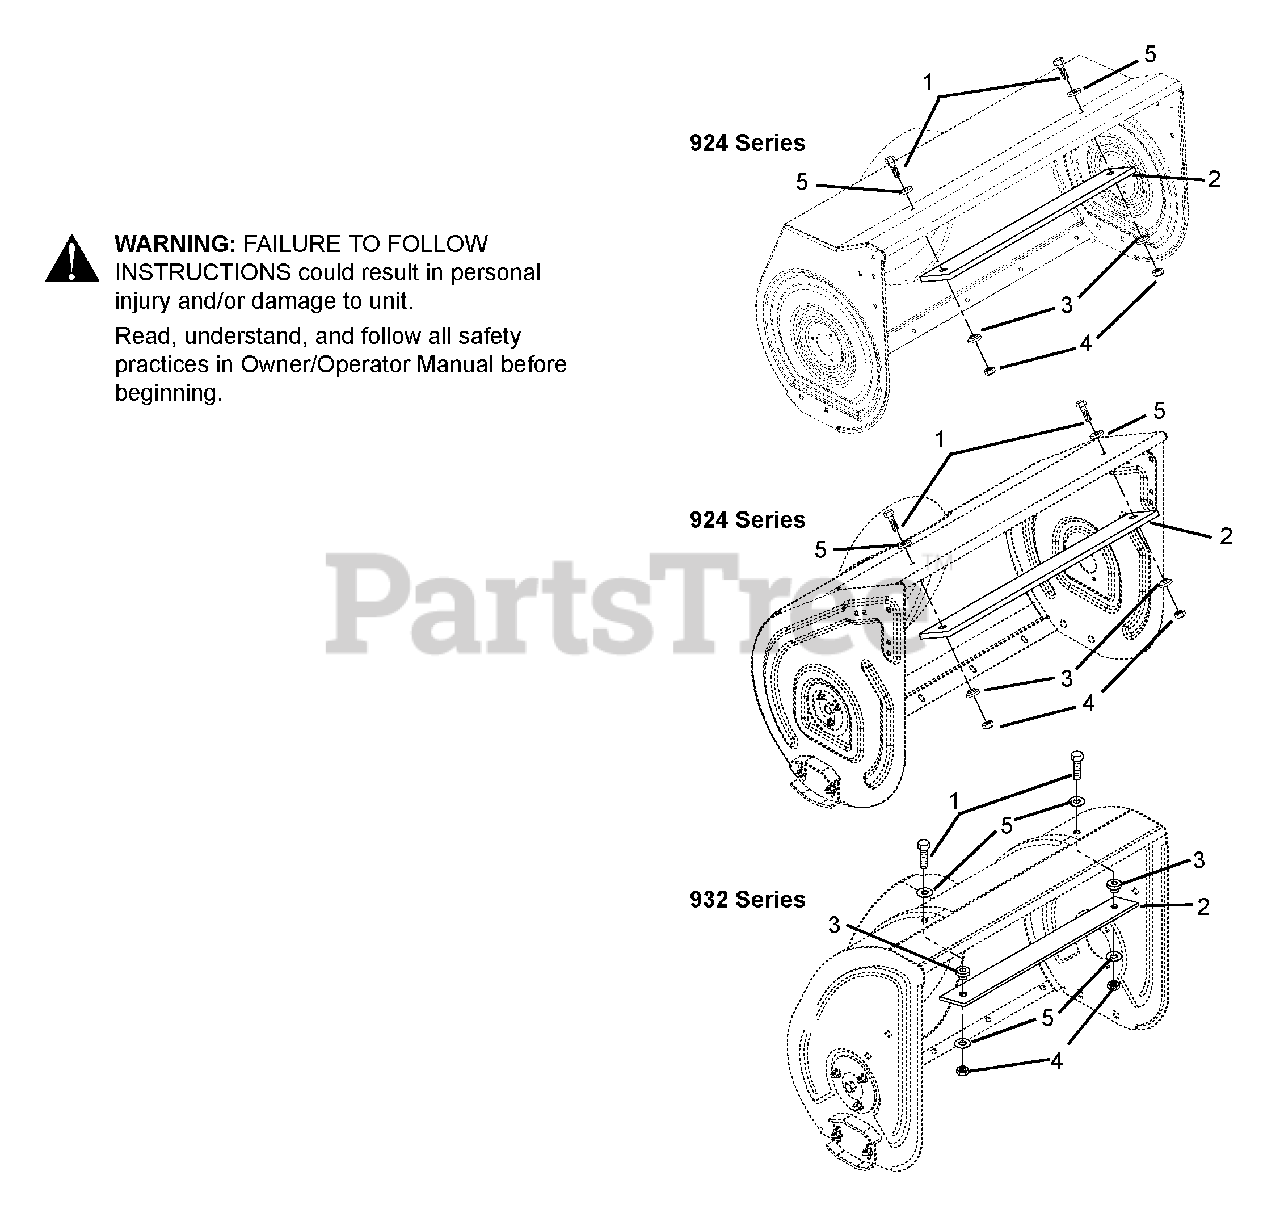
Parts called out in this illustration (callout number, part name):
1	@BLT-HEX .31-18X1.50 GR5 YWZC
2	WEIGHT, AUGER/IMPELLER HSG
3	BSHG, FLG .325X.499X.26X.88
4	@NUT-LK-CTR .31-18 YWZC
5	@WSHR-FL-STL.344X.688X.065YWZC
